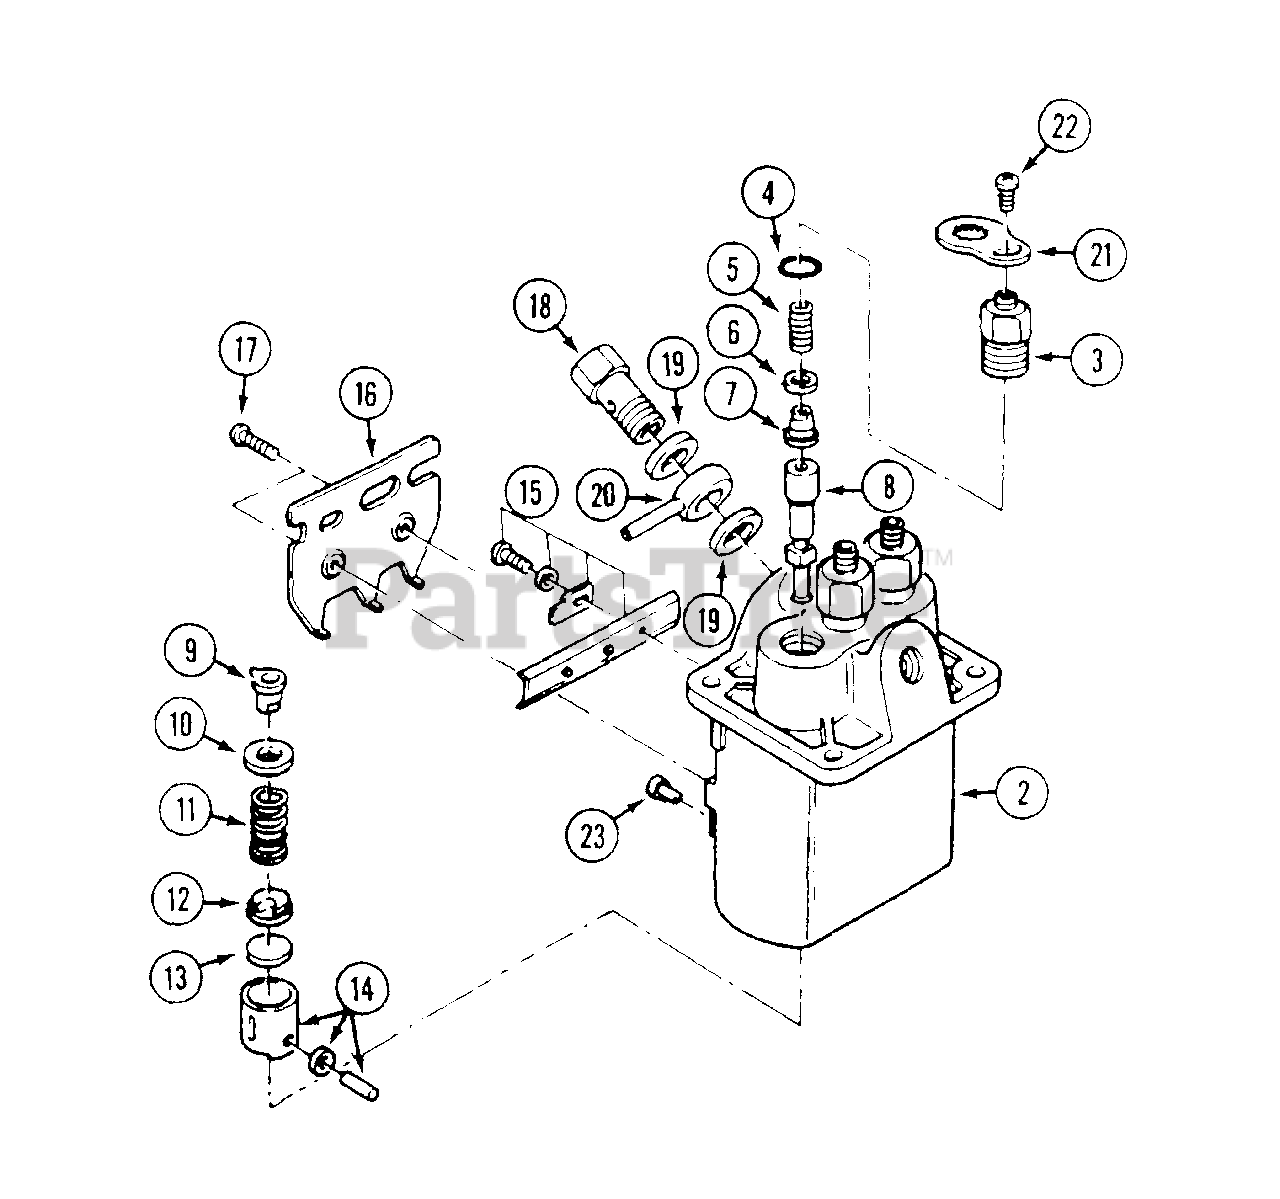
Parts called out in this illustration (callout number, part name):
2	HOUSING
3	HOLDER
4	"O" RING
5	SPRING
6	GASKET
7	VALVE
8	ELEMENT
9	SLEEVE
10	SEAT
11	SPRING
12	SEAT
13	PLATE - shim 1.85mm
14	TAPPET
15	RACK
16	BRACKET
17	SCREW
18	BOLT
19	WASHER
20	NIPPLE
21	PLATE
22	SCREW
23	PIN
